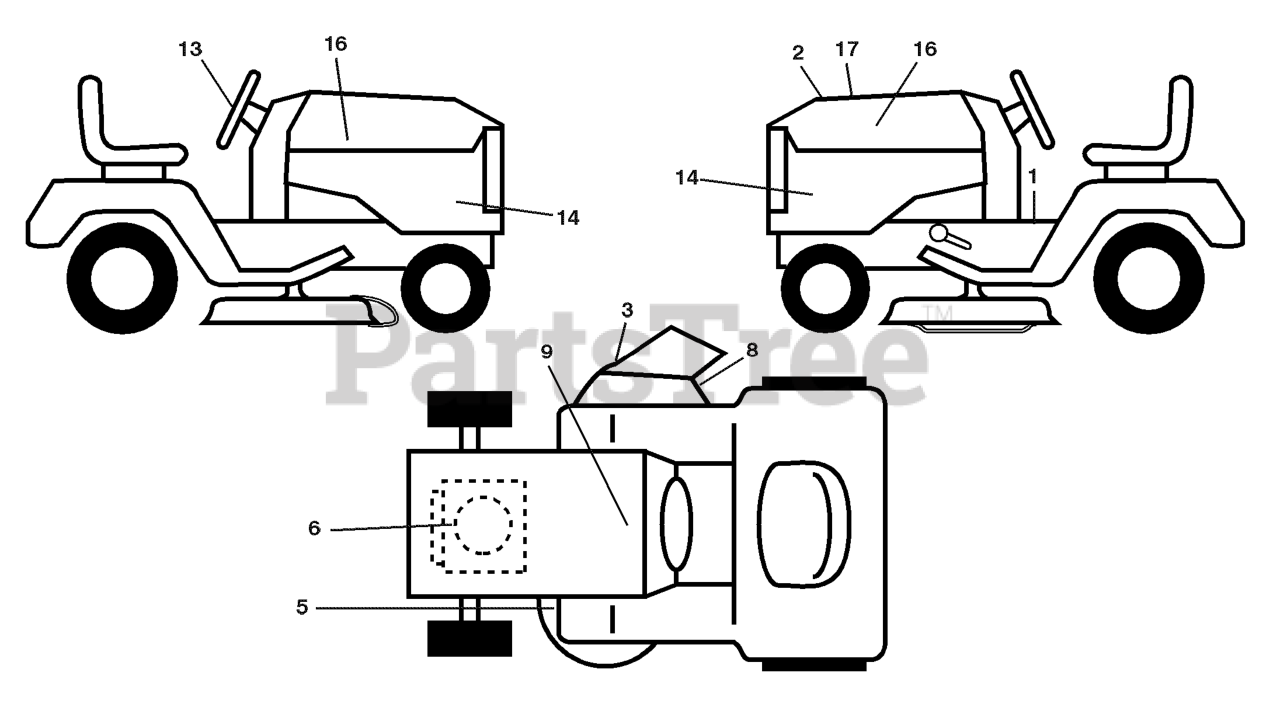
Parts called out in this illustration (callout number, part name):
1	DECAL.FENDER.WARNING.ENG
2	DECAL HOOD CUST. RESP.
3	DECAL.WARN.KEEP.HAND.AWAY
5	DECAL CLUTCH/BRAKE
6	DECAL, ENG. HP
8	DECAL.MOWER.SCH.48/54
9	DECAL BTRY SYMBOLS
13	DECAL.WHEEL.STRG.LGN.H
14	DECAL, PANEL SIDE
16	DECAL.HOOD.NAMELOGO.HUSQ
17	DECAL.REPLACEMENT.960430035
17	DECAL.BYPASS.FENDER.CRD.LT.YT
17	PAD, FOOTREST, LH
17	PAD, FOOTREST, RH
17	Manual, Owner's
